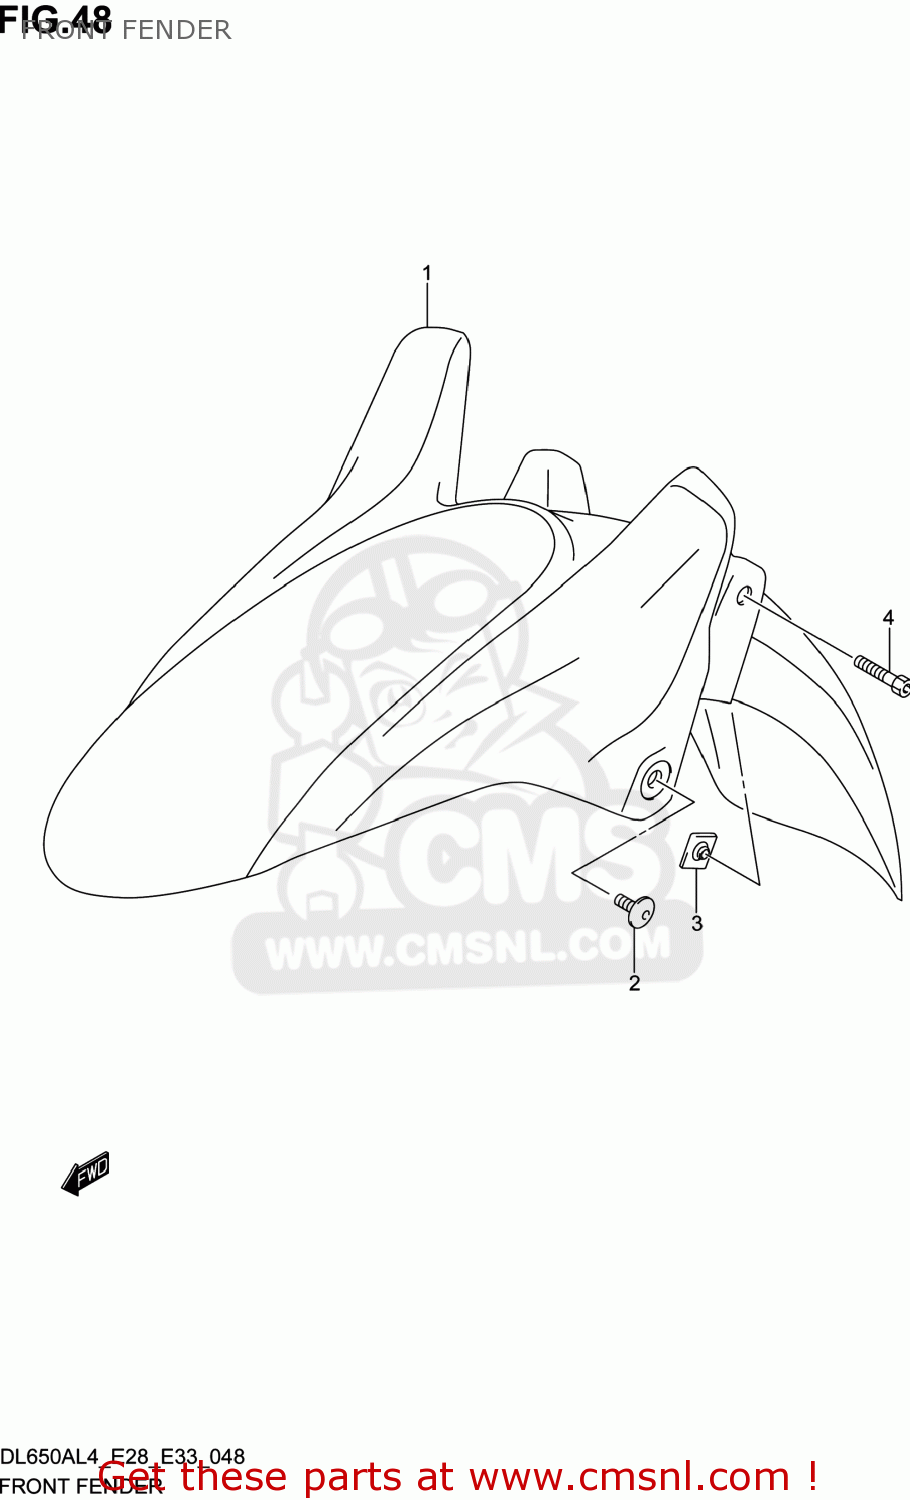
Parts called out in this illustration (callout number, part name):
1	FENDER FRONT DL650A/L2
2	SCREW(6X16)
3	NUT,FR FENDER
4	BOLT(6X30)
